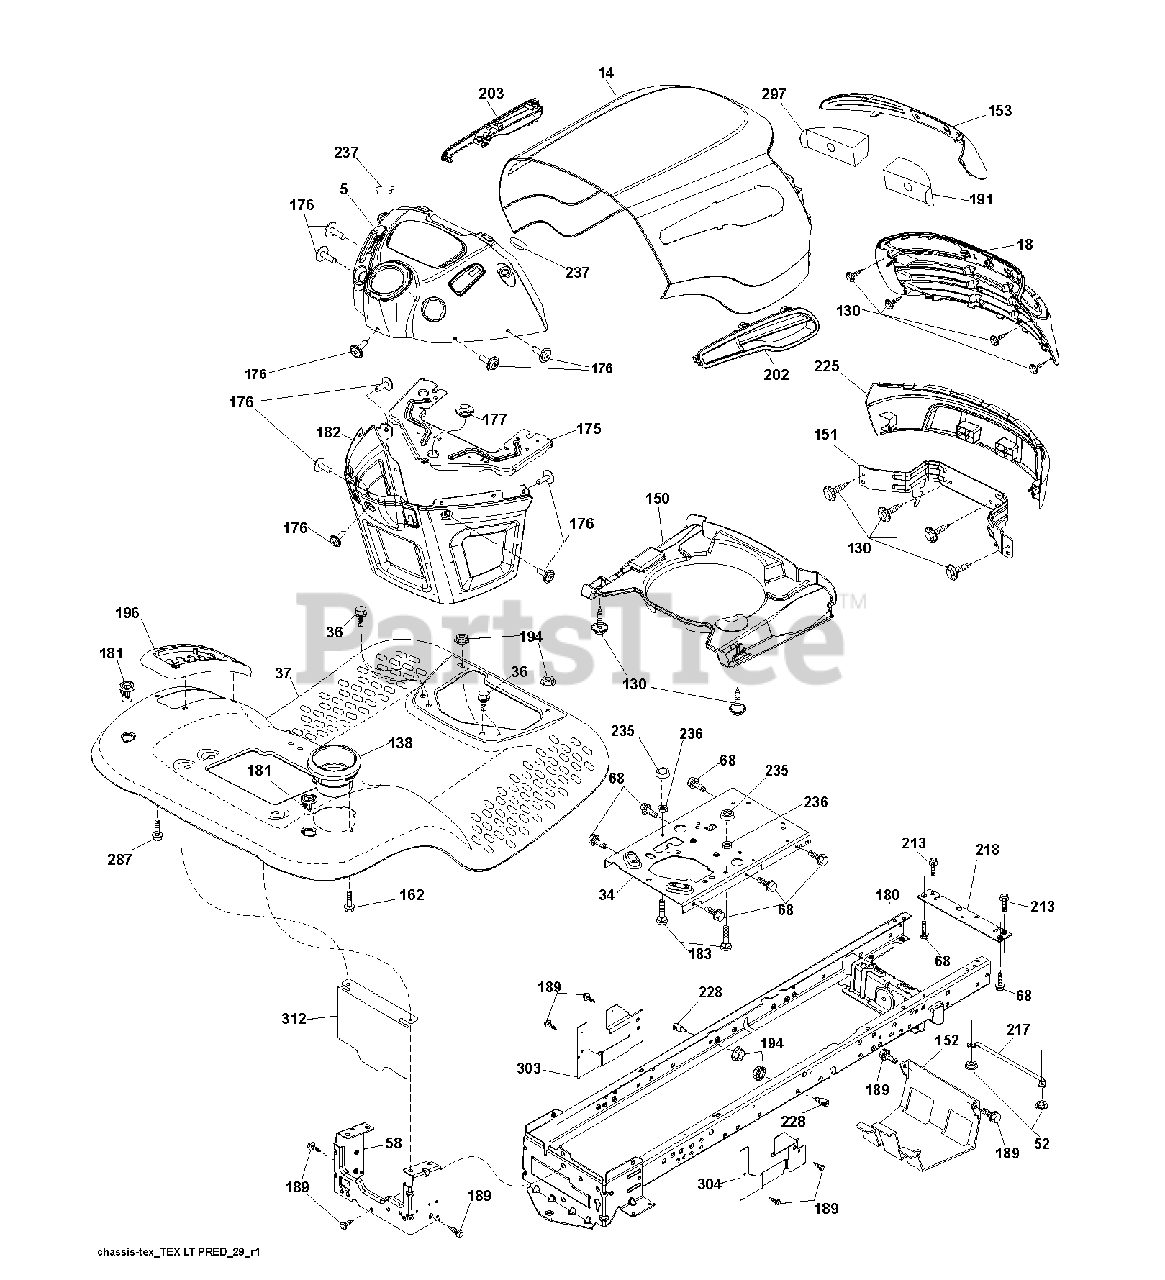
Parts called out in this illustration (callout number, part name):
34	PLATE.ENGINE.WELDED.CHASSIS
36	SCREW 5/16"
52	LOCKNUT
58	DRAWBAR UPPER 2PC SMALL FENDER
130	SCREW.#10 X 0.750.BOS THREAD
138	CUPHOLDER.TL.TEX.BLACK
151	BRACKET.PIVOT.ALPHA.LT
152	SHIELD BROWNING
162	SCREW.HI-LO.CONSOLE
175	CROSSMEMBER
176	SCREW.#10-24X5/8.RN.QU
177	BUSHING STEERING
181	FEND/FTRST.PCH.CPH.NFW
182	DASH.LWER.PREDATOR/HUSQ.LT
183	BOLT.5/16-18X1-1/4 FULL THD
189	SCREW
191	INSERT.REFLECT.PREDATOR.LT.RH
194	NUT LOCK HEX FLANGE 5/16-18
196	CONSOLE.ASM.DECKLFT.BL/RBT.TLT
213	BOLT
217	ROD.PIVOT.HOOD
218	X-PIECE.HOOD.STOP.NON/
228	STUD.FASTNER.W/ANTI-ROTATE
235	SPACER FENDER
236	NUT.CENTERLOCK.5/16-
237	PLUG.MOUNT.CARGO.BLK
297	REFLECTOR.INSERT.PRED.LH.LT
